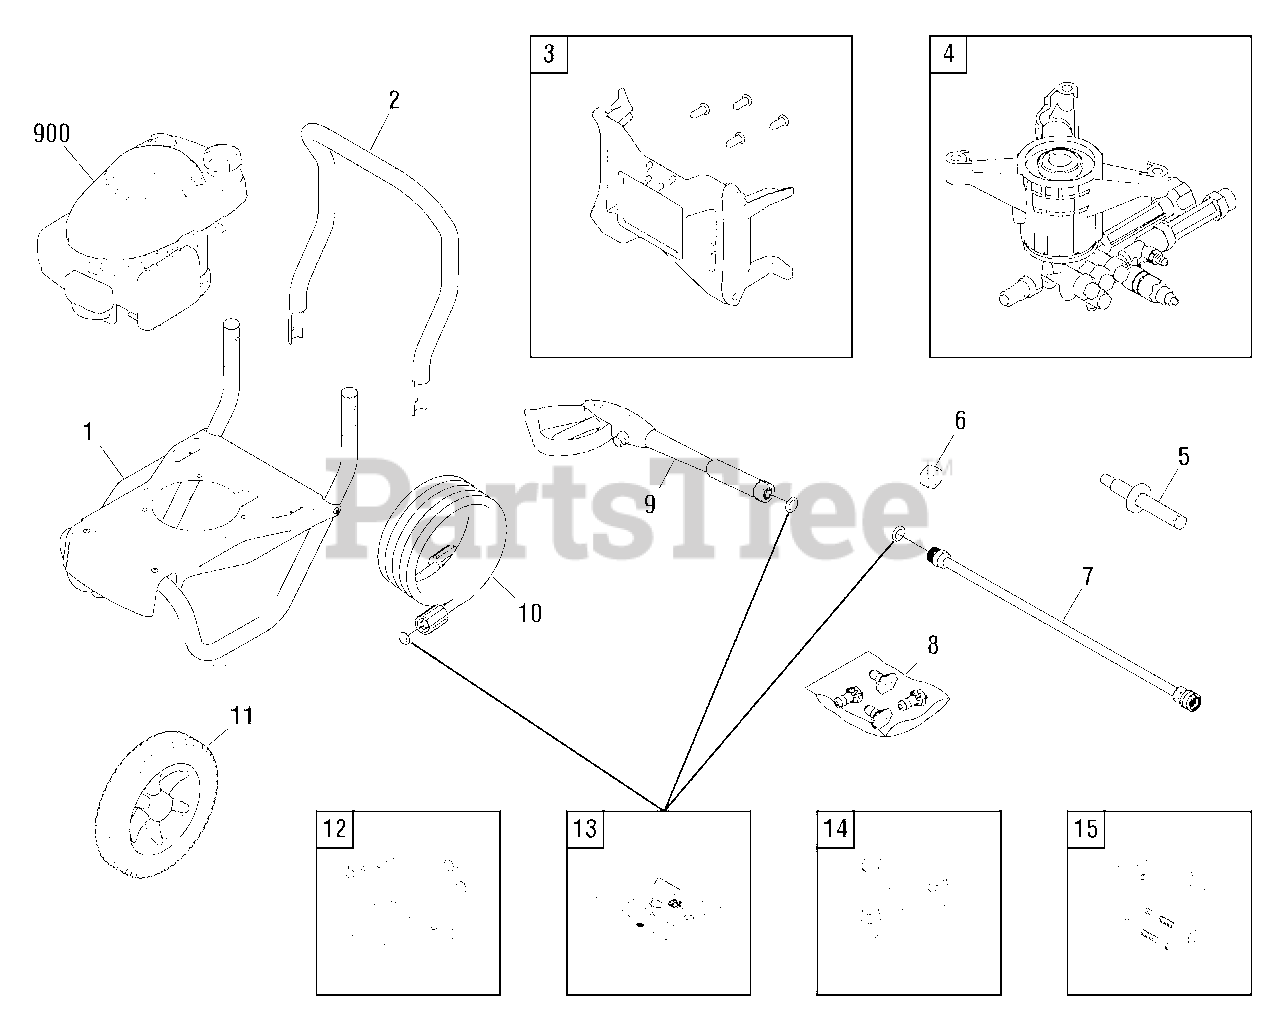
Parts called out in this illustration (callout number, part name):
7	EXTENSION-QC
8	KIT-QC NOZZLE
9	GUN
10	HOSE
12	MOUNT-VIBRATION
14	KIT-HARDWARE PUMP MOUNTING
900	** ENGINE
